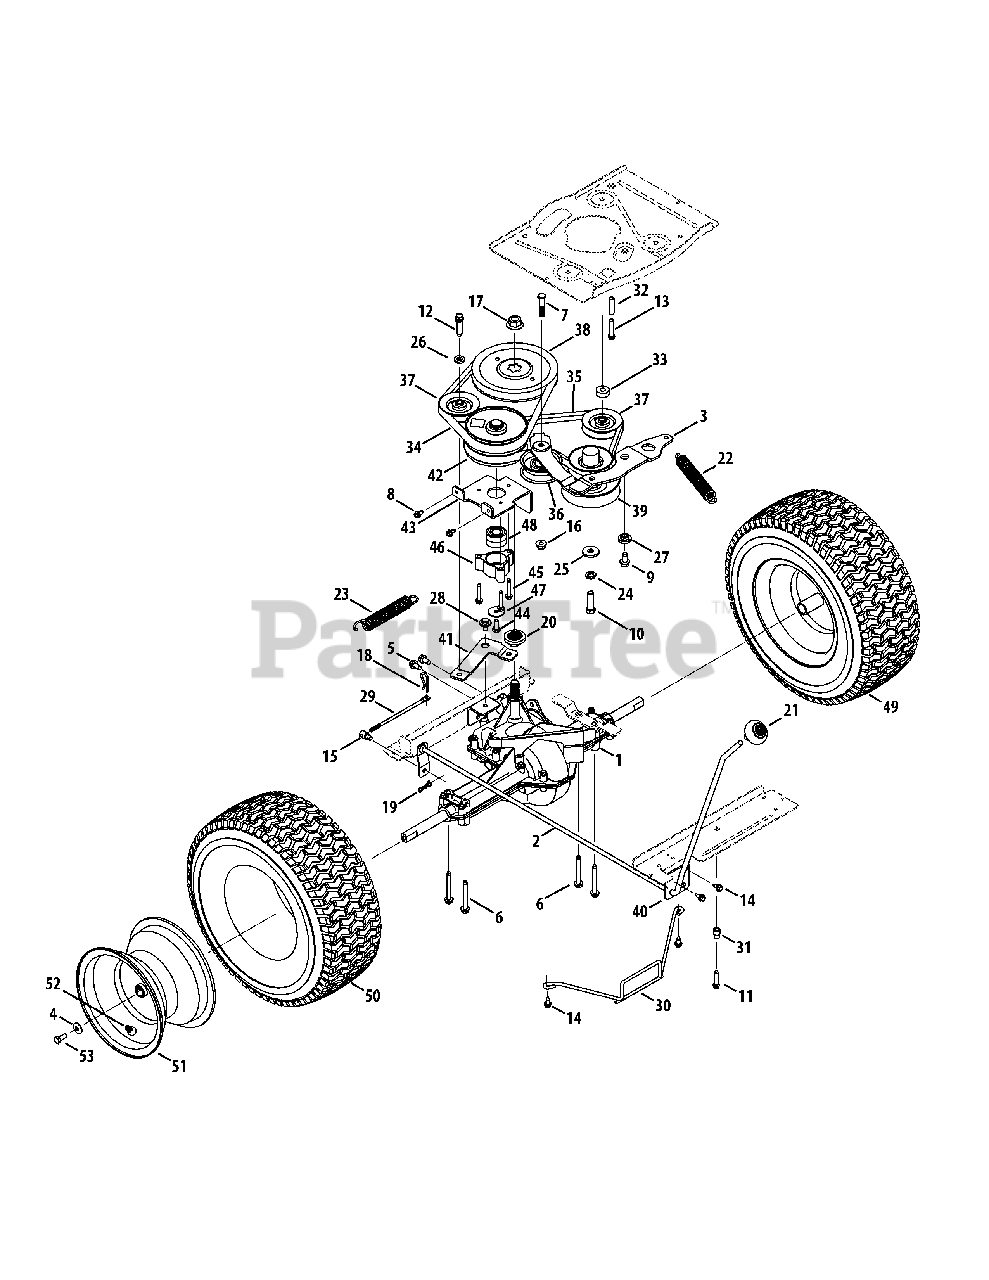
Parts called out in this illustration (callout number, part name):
1	Transmission Assembly
2	Shift Handle Assembly
3	Drive Assembly Idler
4	Beveled Washer, .340 x .872 x .060
5	Tap Screw, 5/16-18, .750
6	Tap Screw, 5/16-18, 2.50
7	Hex Head Scew, 3/8-16, 1.62
8	Tap Scew, 1/4-20, 0.500
9	Tap Screw, 3/8-16, 0.750
10	Hex Head Screw, 7/16-20, 1.50
11	Tap Screw, 1/4-20, 1.250
12	SEMS Tap Screw, 3/8-16, 1.500
13	Tap Screw, 1/4-20, 1.625
14	Tap Screw, 1/4-20 x .625
15	Adjustable Ferrule, 1/4-20 X 1.00
16	Flange Lock Nut, 3/8-16
17	Flange Nut, 9/16-18
18	Internal Cotter Pin, .125 Dia.
19	Bow-Tie Cotter Pin
20	Pulley Hub, 5/8 Spline
21	Shift Knob
22	Extension Spring, .94 Dia. X 6.74 Lg.
23	Extension Spring, .97 OD X 6.18
24	Split Lock Washer, 7/16
25	Flat Washer, .450X1.250X.164
26	Flat Washer, .407X.812X.135
27	Shoulder Spacer, 1.00 X .38 X .38
28	Shoulder Spacer, .560x.165, 5/16-18
30	Deck Belt Keeper, 30"
31	Stepped Spacer, .265 ID X .750
32	Spacer, .260 X .372 X 1.420
33	Spacer, .406 ID X 1.00 OD X .38
34	V-Belt, 5L x 35.25
35	V-Belt, 5L x 35.28
36	Flat Idler Pulley, 2.75 OD
37	V-Type Idler Pulley, 3.06
38	V-Type Pulley, 6.56
39	Engine Pulley, 4.46 / 3.39
40	Front Support Shift Bracket
41	Rear Idler Arm Bracket
42	Variable Speed Pulley Assembly
43	Variable Bracket
44	Hex Head Lock Screw, 5/16-24 x .750
45	Tap Screw, 1/4-20 x 1.500
46	Bearing Cup
47	Flat Washer, .330x1.250x.060
48	Ball Bearing, 17 X 40 X 12
49	Complete Wheel Assembly
50	Tire, 16 x 6.5 x 8 Sq. Shoulder
51	Rim Assembly, 8.0 x 5.38
52	Air Valve
53	Hex Head Screw, 5/16-24, 7.50
